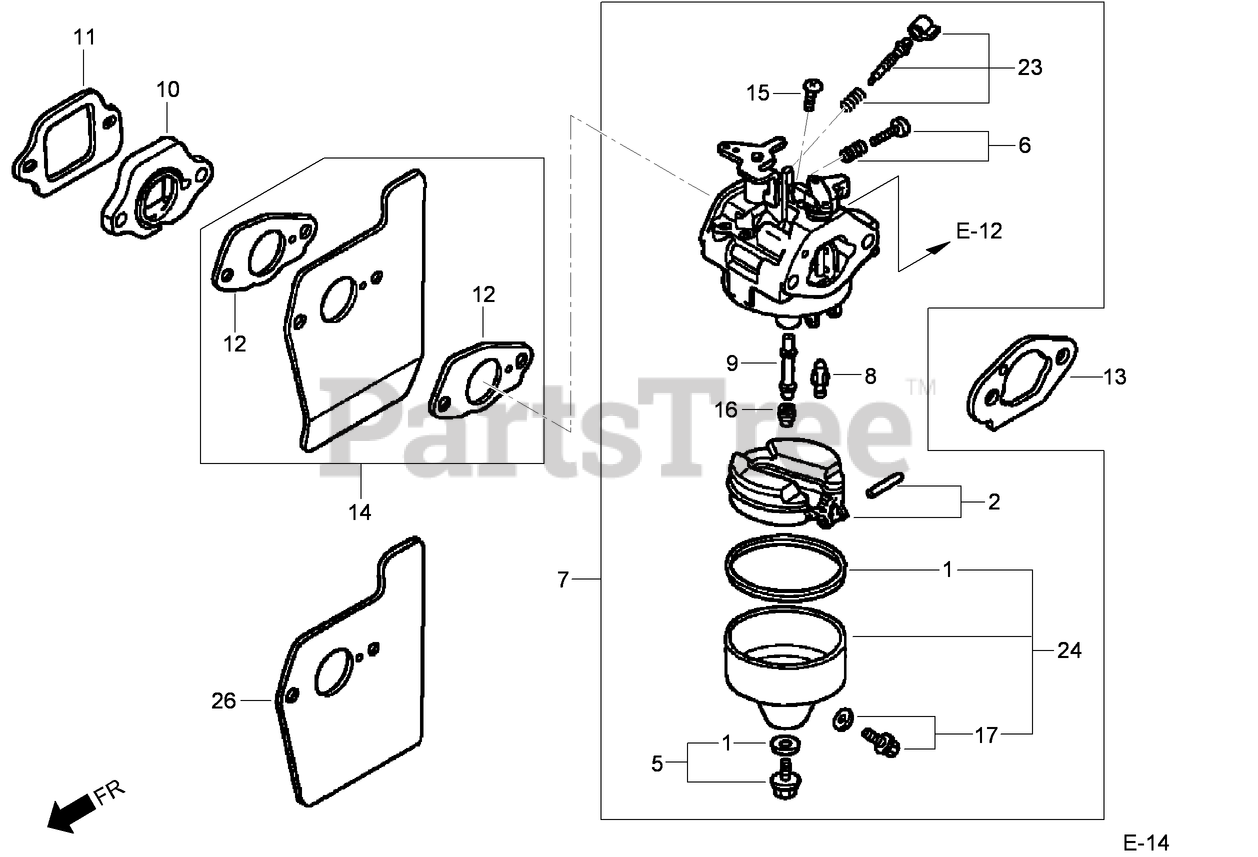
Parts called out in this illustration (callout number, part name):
1	GASKET SET
2	FLOAT SET
5	SCREW SET
6	SCREW SET (THROTTLE STOP)
7	CARBURETOR ASM (B B62B E) (engine serial numbers up to 3698326)
7	CARBURETOR ASM (B B62W A) (engine serial numbers starting at 3698327)
8	VALVE-FLOAT
9	NOZZLE-MAIN
10	INSULATOR-CARBURETOR
11	GASKET-INSULATOR
12	GASKET-CARBURETOR (engine serial numbers up to 6349022)
13	GASKET-CARBURETOR
14	GUIDE-AIR (engine serial numbers up to 6349022)
15	SCREW-PAN (5X6)
16	JET-MAIN (No.60) (Optional Equipment)
16	JET-MAIN (No.62) (Optional Equipment)
16	JET-MAIN (No.65)
17	DRAIN SCREW SET
23	SCREW SET
24	FLOAT CHAMBER SET (engine serial numbers up to B B62Z A)
26	GUIDE-AIR (engine serial numbers starting at 6349023)
